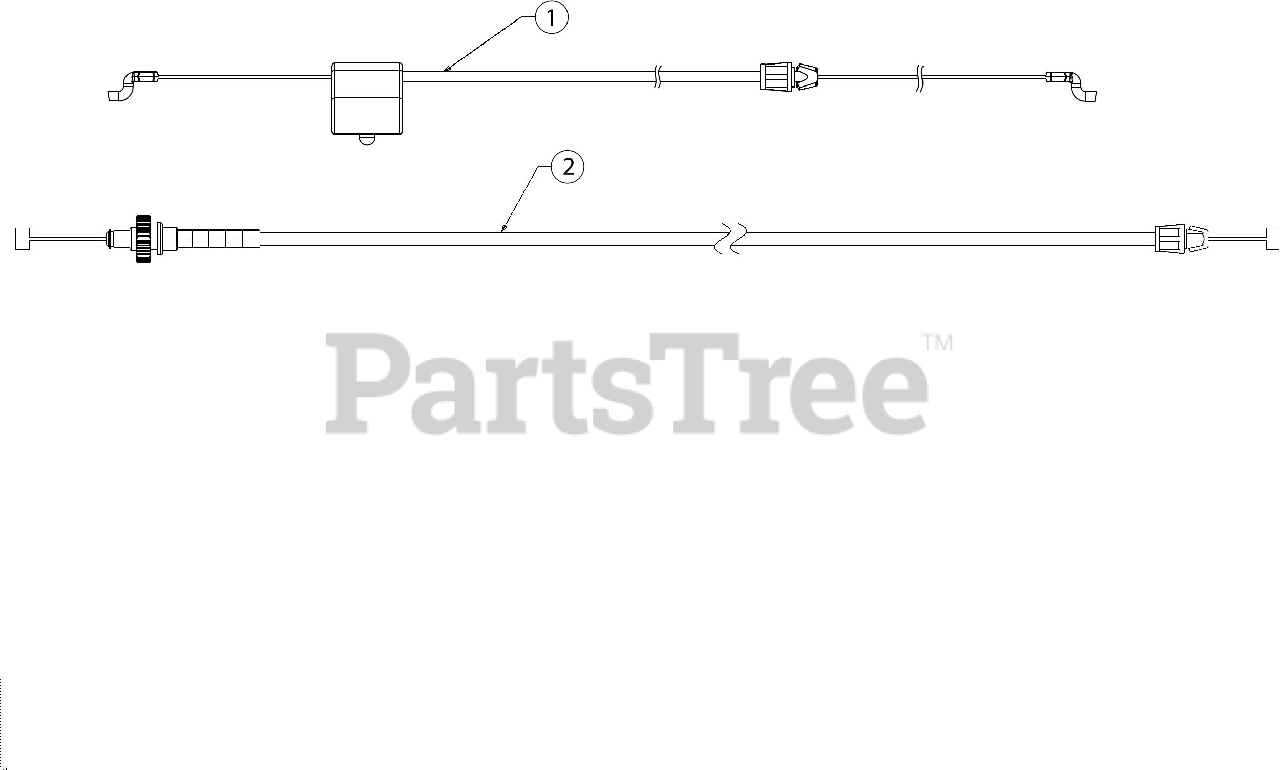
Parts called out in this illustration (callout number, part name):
1	SPEED SELECT CABLE W/ELBOW
2	SPEED ADJUSTMENT CABLE 56.25"
3	CONTROL CABLE 37.58"
